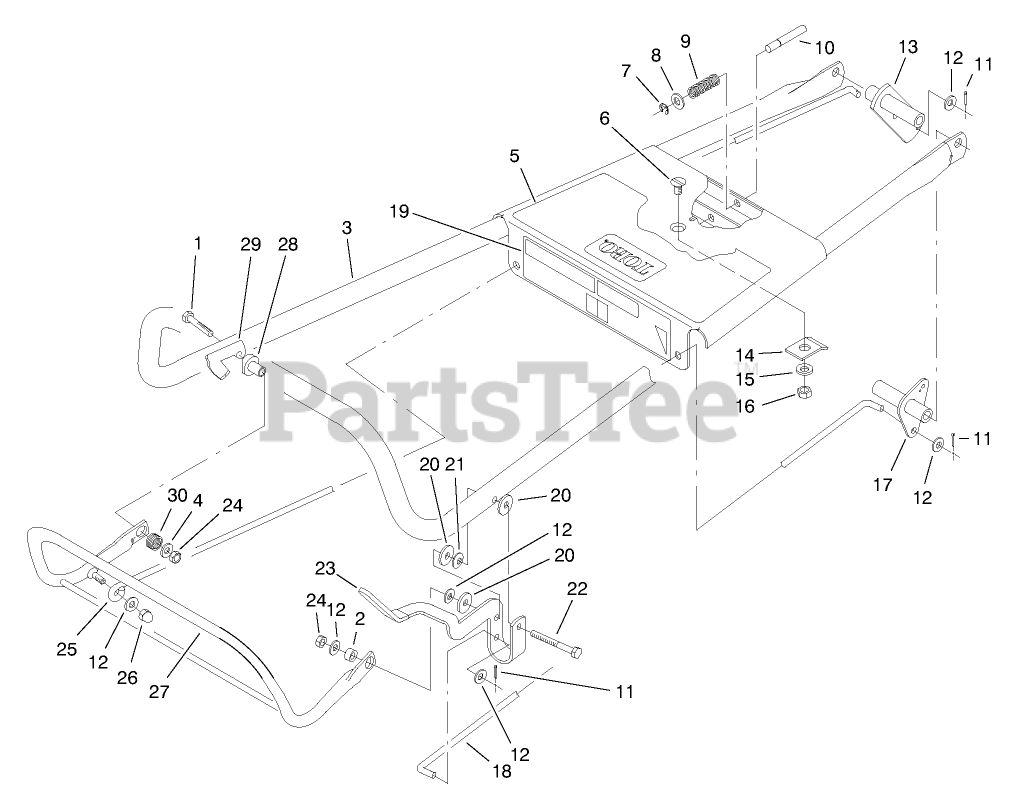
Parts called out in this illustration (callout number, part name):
1	SCREW-CARR
2	Handle-Section Lower (Incl. Ref. #25)
3	TIE-CABLE
5	SCREW-HH
6	NUT-LOCK, NI
7	SCREW-TAP
8	BRAKE CAM
9	BRACKET-STOP, BAIL
12	STOP-PIVOT
13	SP CONTROL BAIL
14	SCREW-HH
16	CABLE - THROTTLE
18	DECAL - CONTROL PANEL
20	CONTROL - GROUND SPEED
21	Panel-Control (Incl. Ref. #18, & 24)
23	BAIL-ENGINE CONTROL
24	DECAL - CONSOLE
25	DECAL - OPERATION
26	CABLE - CONTROL
27	CLIP-STARTER
28	HANDLE-START
29	GUIDE-ROPE
30	SCREW-HANDLE
31	BRACKET-ANCHOR, CABLE
32	NUT-LOCK, NI
33	Handle-Upper
35	WASHER-CURVED
36	Bracket-Traction Cable
37	TRACTION CABLE ASM
46	SCREW-HH
49	NUT-LOCK, NI
51	WASHER-PLAIN
